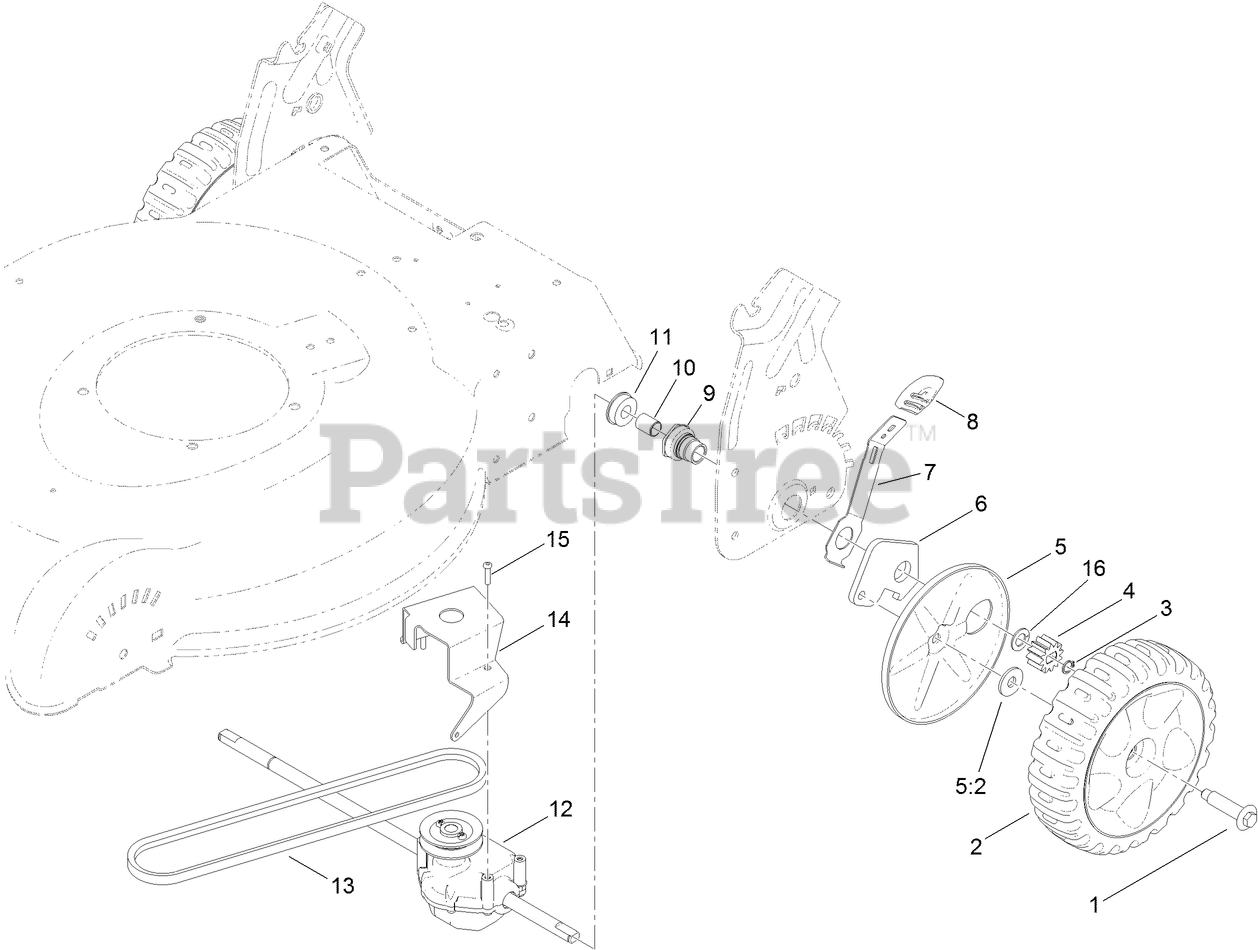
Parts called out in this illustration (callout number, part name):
1	BOLT-SHOULDER
2	8 INCH WHEEL GEAR ASM
3	RING-RETAINING
4	GEAR-PINION
5:2	WASHER-STEPPED
6	ARM-PIVOT, REAR
7	ARM-SPRING
8	KNOB-LEVER, HOC
9	RETAINER-BUSHING, HOC
10	BUSHING-SLEEVE
11	BEARING-BALL
12	TRANSMISSION ASM
14	BRACKET-TRANSMISSION
15	SCREW-PLASTITE
16	WASHER-THRUST
